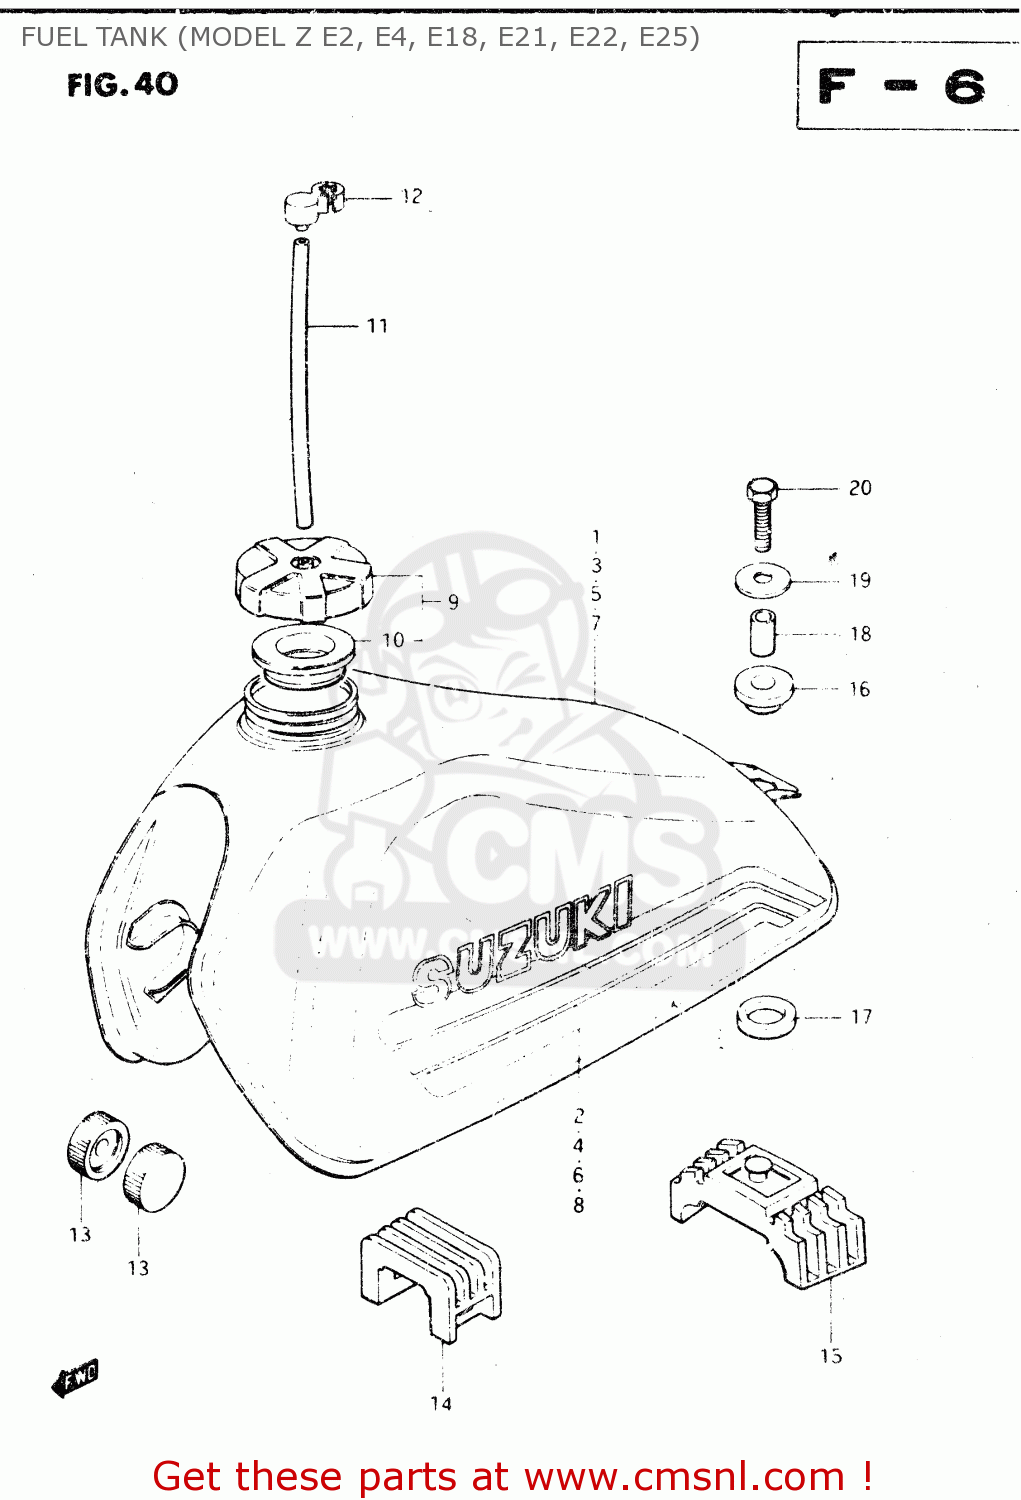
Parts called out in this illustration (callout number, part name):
1	TANK, FUEL (BLACK)
2	TAPE SET
3	TANK FUEL (BLUE)
4	TAPE SET
5	TANK, FUEL (YELLOW)
6	TAPE SET,FUEL TANK
7	TANK, FUEL (RED)
8	TAPE SET
9	CAP SET,FUEL TANK
10	GASKET (NAS)
11	HOSE
12	CLAMP,FUEL TANK BREATHER HOSE
13	CUSHION
14	CUSHION,TANK UPR FR
15	CUSHION,FUEL TANK,REAR
16	CUSHION
17	CUSHION
18	SPACER(8.5X12X19)
19	WASHER (8.5X29X1.6)
20	BOLT (8X30)
